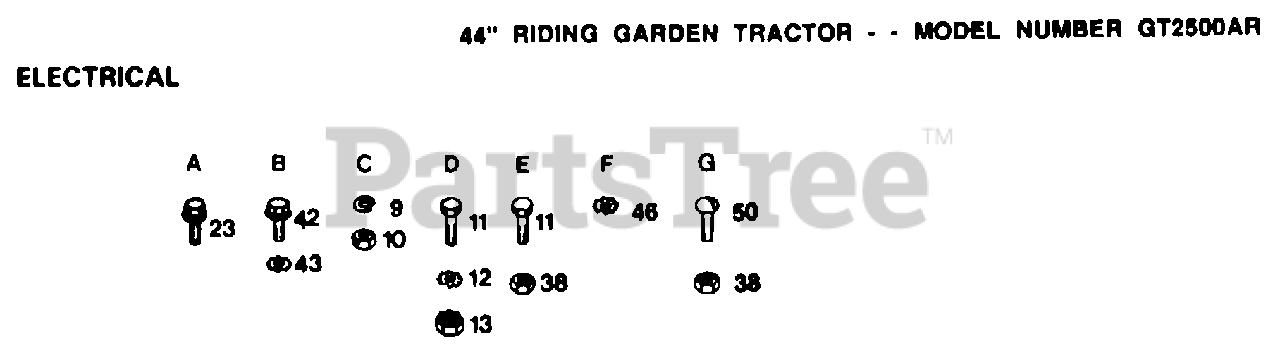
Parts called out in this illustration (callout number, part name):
10	NUT
11	BOLT
13	NUT
23	SCREW
42	SCREW
43	"NUT,KEPS"
46	LOCKWASHER
50	BOLT
